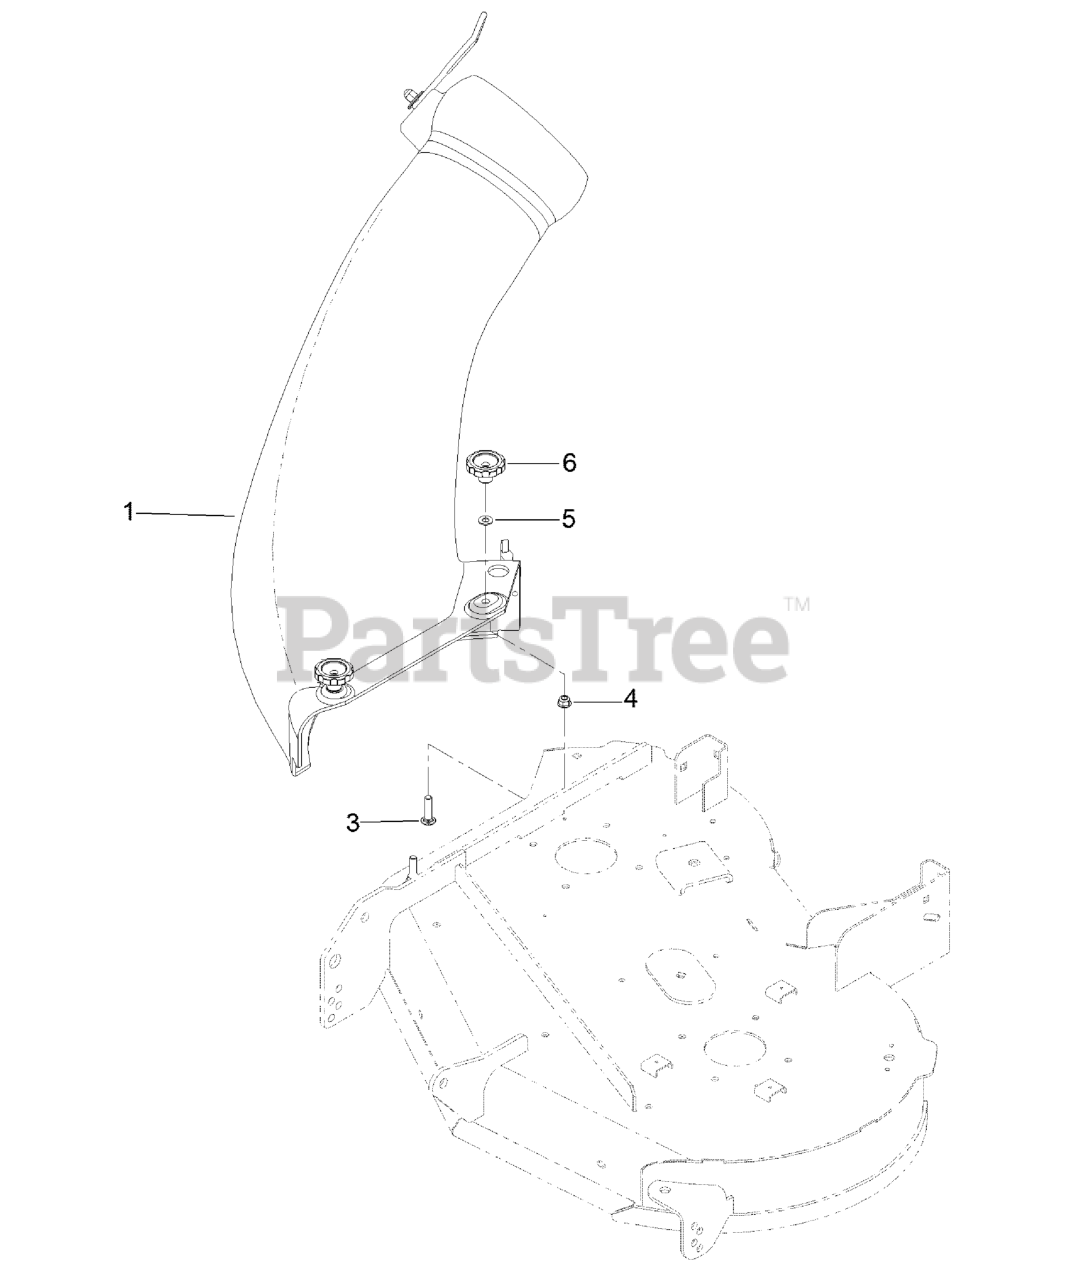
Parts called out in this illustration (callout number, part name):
1	34 INCH CHUTE ASM
3	BOLT-CARRIAGE 5/16-18 X 1 3/8 SHORT NECK
4	NUT-HF, NI
5	WASHER-PLAIN
